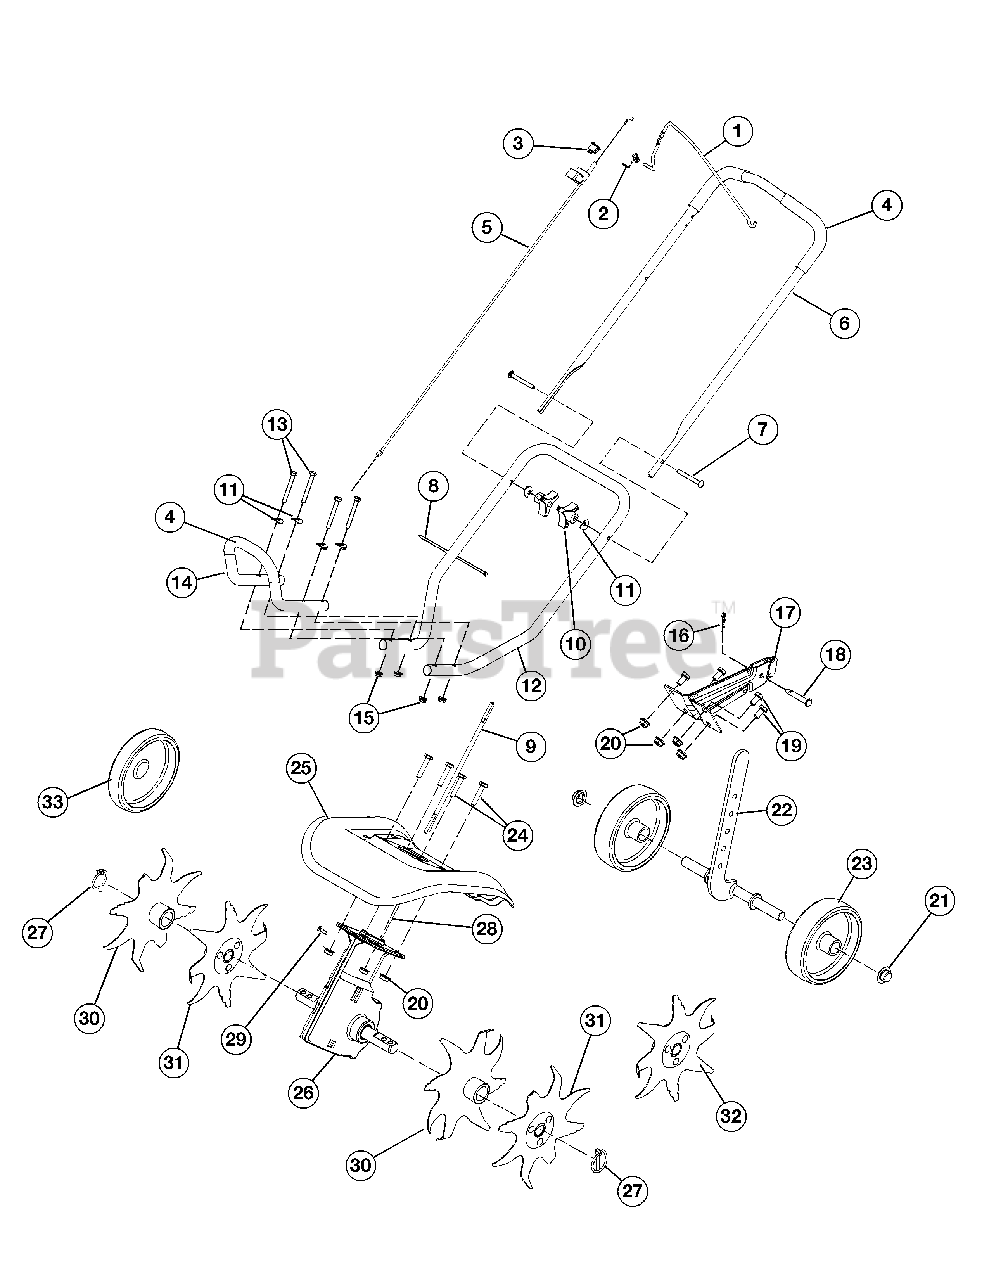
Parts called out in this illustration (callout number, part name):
1	Throttle Control
2	Torsion Spring
3	On/Off Switch
4	Foam Grip
5	Throttle Cable
6	Upper Handle
8	Cable Tie
9	Flex Shaft
11	Shoulder Washer
12	Lower Handle
13	Screw
14	Front Handle
15	Lock Nut
16	Cotter Pin
17	Tailpiece Bracket Assembly
18	Clevis Pin
19	Cap Screw
20	Lock Nut
21	Cap Push
22	Wheel Support Bracket Assembly
23	Wheel
24	Cap Screw
25	Tine Shield
26	Gear Box Assembly
27	Click Pin
28	Drive Shaft Housing
29	Sleeve Retaining Bolt
30	Tine RH outer/LH inner
31	Tine LH outer/RH inner
32	Edger Tine
33	Edger Wheel
